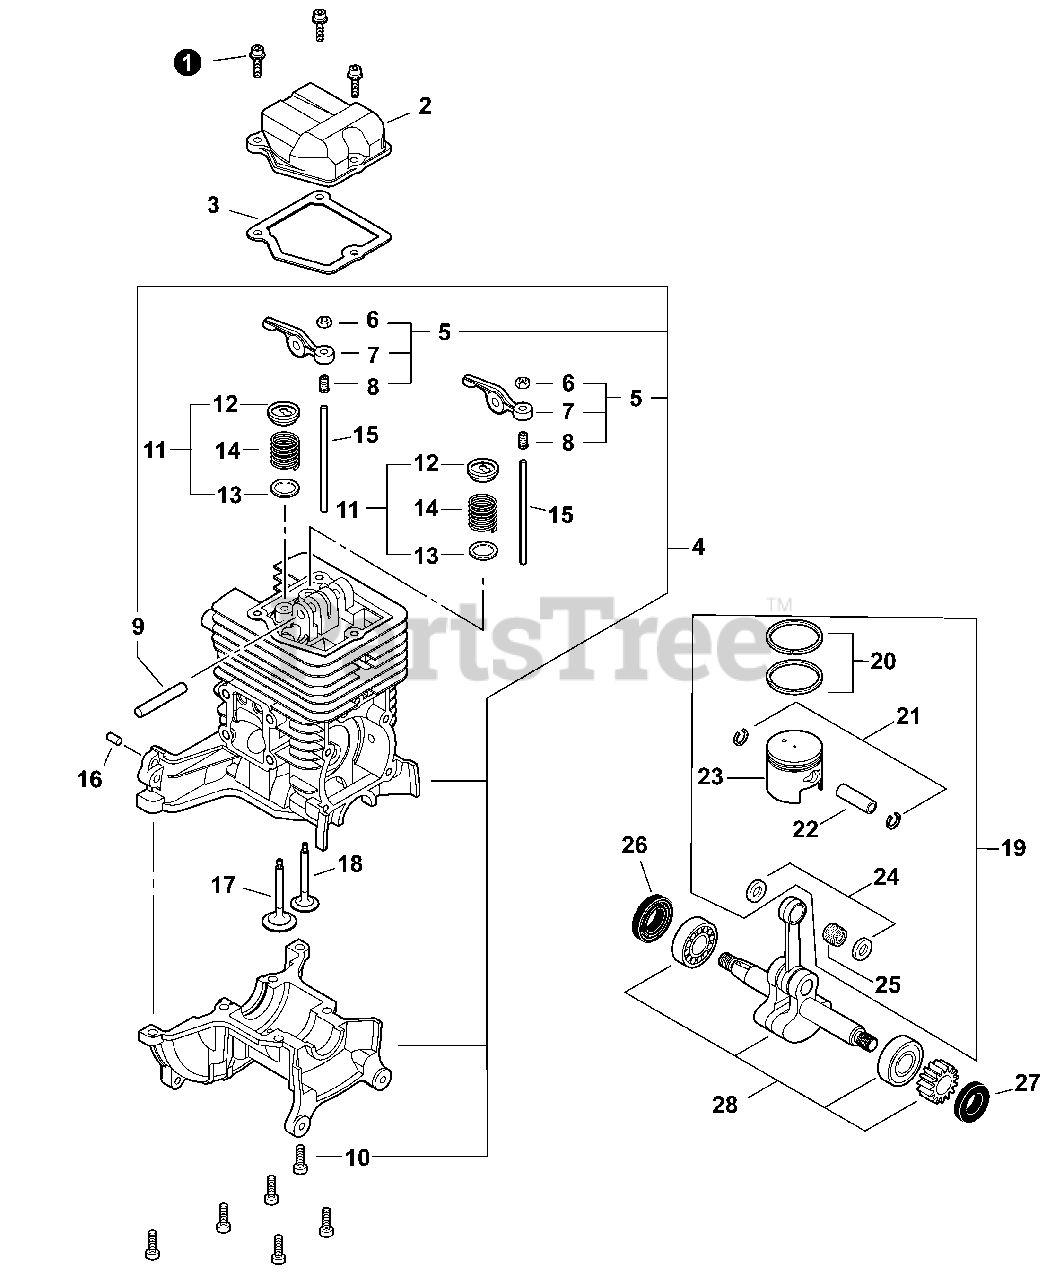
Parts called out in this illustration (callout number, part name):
1	BOLT M4×14
2	COVER, ROCKER ARM
3	GASKET, ROCKER ARM
4	CYLINDER & CRANKCASE ASSY
5	ARM ASSY, ROCKER
6	NUT, ADJUSTER LOCK 5
7	ARM, ROCKER
8	SCREW, ADJUSTER
9	SHAFT, ROCKER ARM Ø5×31.8 MM
10	BOLT 5×16
11	RETAINER SET, VALVE
12	RETAINER, VALVE
13	WASHER, VALVE 9
14	SPRING, VALVE
15	PUSHROD
16	PIN, LOCATING 4×8
17	VALVE, INTAKE
18	VALVE, EXHAUST
19	PISTON KIT
20	RING, PISTON
21	RING, SNAP
22	PIN, PISTON
24	WASHER, THRUST 9
25	BEARING, NEEDLE 9
26	SEAL, OIL 12
27	SEAL, OIL 12
28	CRANKSHAFT ASSY
